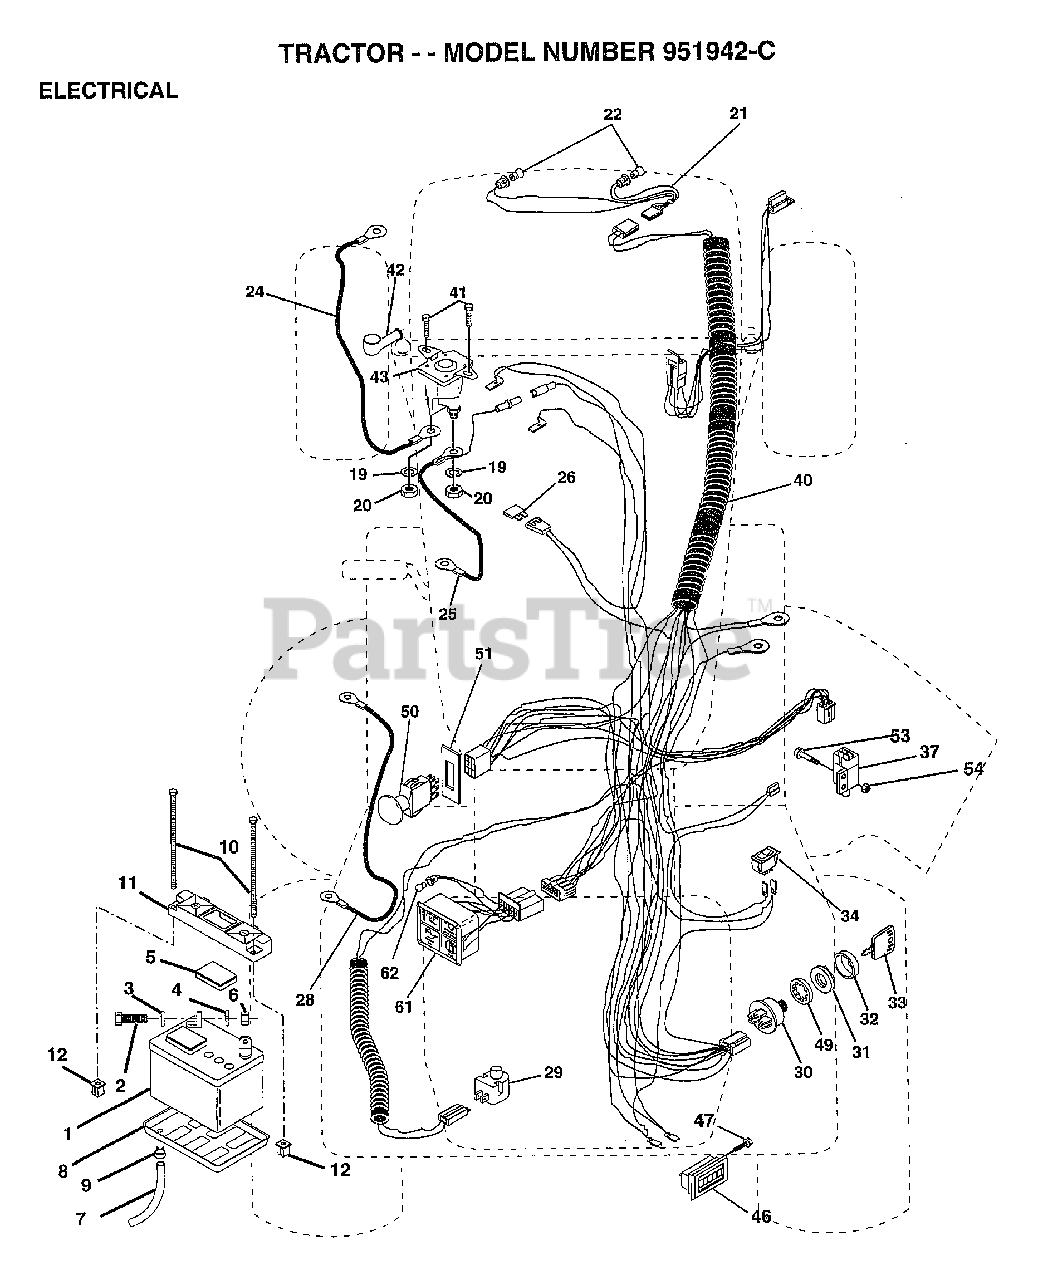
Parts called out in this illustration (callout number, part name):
1	DRY BATTERY 35AMP
2	BOLT LT
3	LOCKWASHER
4	WASHER
5	"CAP,BATTERY "
7	"DRAIN TU T, BATT"
8	"TRAY T, BATTERY"
9	HOSE CLAMP T
20	NUT
21	"HARNESS,LIGHT SOC"
22	HEADLAMP BULB
24	CABLE.BATY.22.RED
25	CABLE.BATRY.4GA.
28	CABLE.BATRY.4GA.
29	SWITCH SEAT
32	COVER KEY SWITCH
33	KEY MLD GEN DELTA
34	SWITCH LT
37	SWITCH INTERLOCKT
41	SCREW
46	HOUR METER T
47	SCREW
49	LOCKWASHER
51	RING RETAIN PTO
53	SCREW
54	"NUT,KEPS"
61	LIGHT.PKG.ASM.
62	BULB LIGHT T
